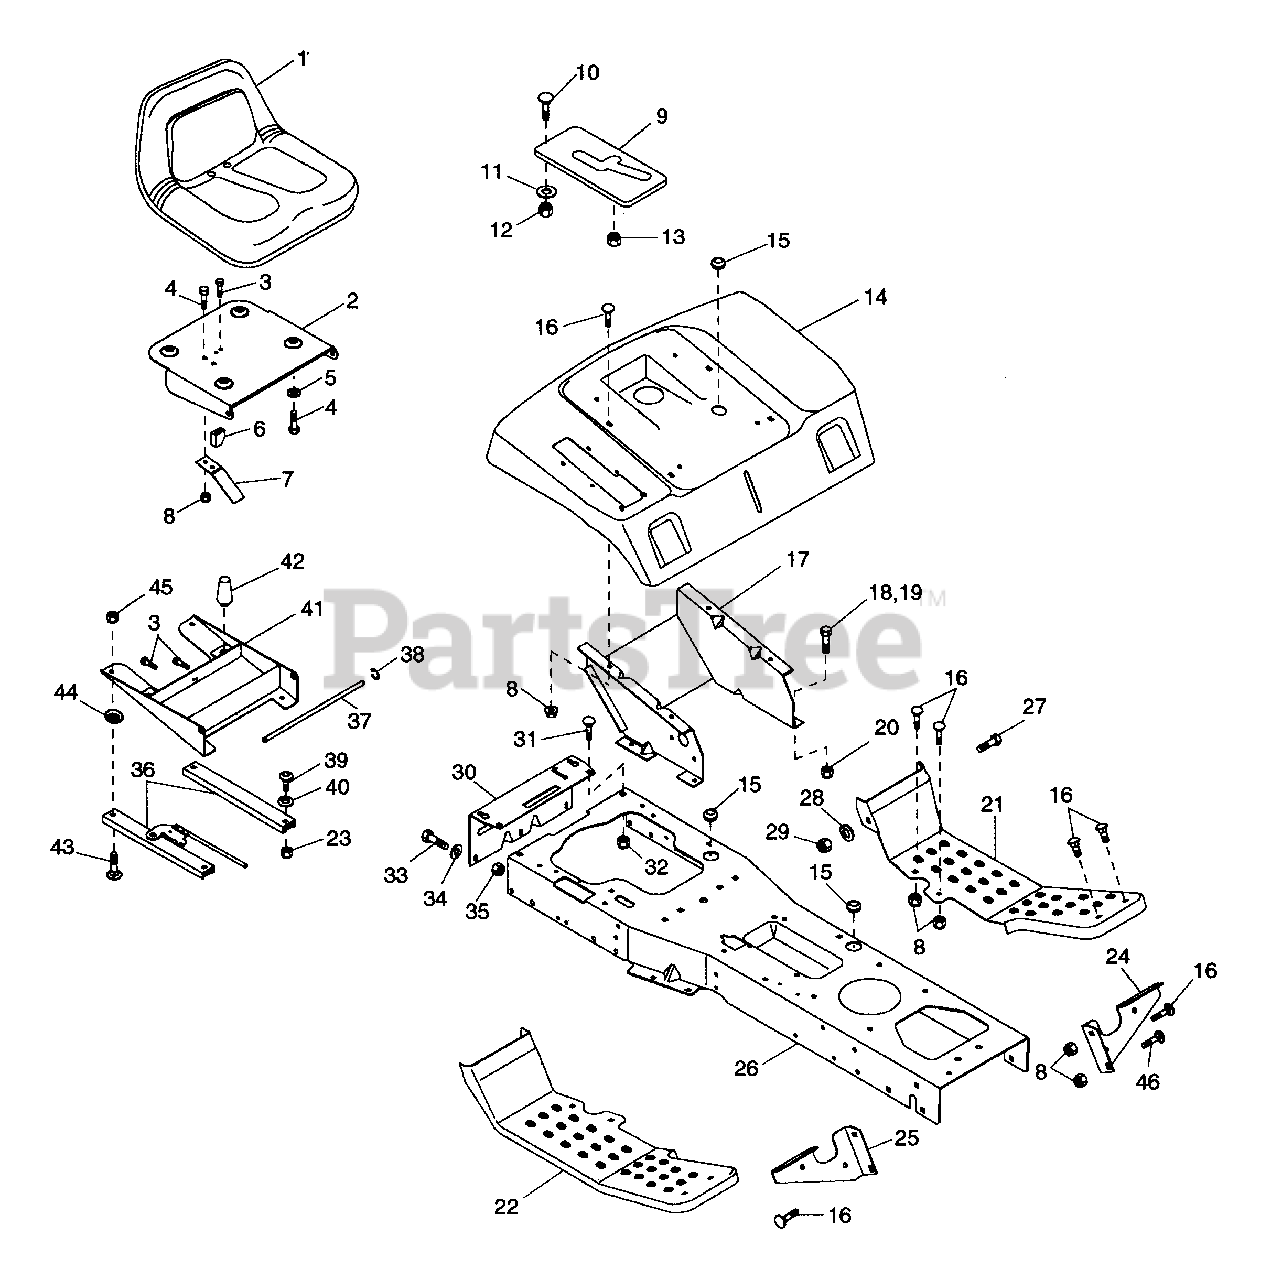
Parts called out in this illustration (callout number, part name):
1	SEAT- V-560
2	SEAT PIVOT PLATE
3	SCR-TAP 12-24X.50 HWH PL TR
4	BLT-HEX .31-18X.75 PL GR2
5	WSHR-LK .312X.097 PL HVY
6	ACTUATOR- PLASTIC
7	SPRING PLATE
8	NUT-FLG. .312-18 PL
9	INSERT
10	SCR-MCH .25-20X .75 CRFL PL
11	WSHR-FL-STL.281X.62X.065 PL
12	NUT-LK-CTR .250-20 PL
13	NUT-SELF-THRDNG FITS.25 STUDPL
14	REAR DECK- YT GEAR
14	REAR DECK- HYDRO
15	GROMMET 1.0ID X 1.38 OD
16	BLT-RDHDSQNK .312-18X.62SHTPL
17	DECK SUPPORT
18	BLT-HEX .31-18X.88 PL GR2
19	BLT-HEX .31-18X.63 PL GR 2
20	NUT-LK .312-18 GR A PL
21	FOOTREST LH
22	FOOTREST RH
23	NUT-HEX .312-18
24	L. FOOT REST BRACE
25	R. FOOT REST BRACE
26	MAIN FRAME
27	BLT-HEX .25-20X.63 PL GR2
28	WSHR-LK .250X.077 HVY PL
29	NUT-HEX .250-20 PL
30	DRAW BAR
31	BLT-RDHDSQNK .375-16X.75 GR5PL
32	NUT-LK-CTR .375-16 GR A PL
33	BLT-HEX .31-18X.75 PL GR5
34	WSHR-FL-STL.312X.734X.065PL
35	NUT-LK-TOP .312-18 GR C PL
36	SEAT SLIDES -(RAME TAK-3010-4)
37	PIVOT ROD
38	RG-RTNG-EXT .375X.035 TYP E
39	SCR-CAP BTHD.31-18X.50 GR5 YZ
40	WSHR-LK-EXT .313X.030 PL
41	SEAT BOX
42	SEAT SPRING BUMPER
43	BLT-RDHDSQNK .31-18X1.0 SHT PL
44	SEAT SLIDE SPACER
45	NUT-LK-NYL.312-18 PL
46	BLT-RDHDSQNK .31-18X1.0 SHT PL
46	BELT FINGER
